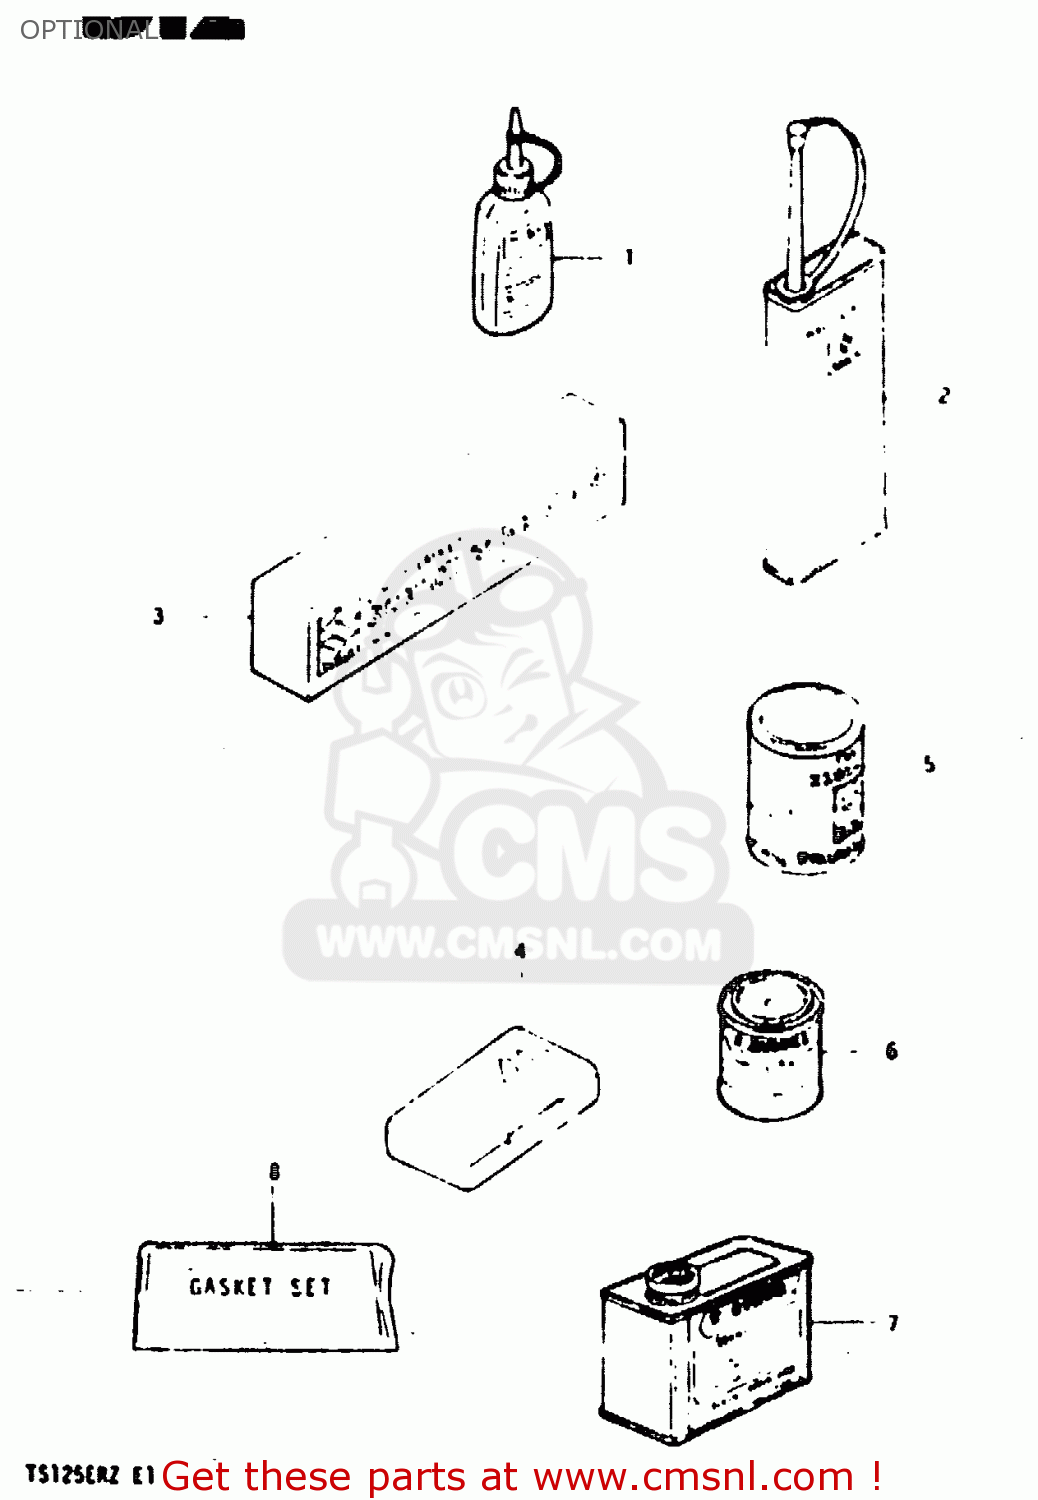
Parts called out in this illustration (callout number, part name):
1	THREAD LOCK NO.1342
2	THREAD LOCK NO.1401 CLEAR 200G
3	BOND 1104
4	TUBE REPARING TOOL
5	GREASE(C)EP2 LITHIUM 150G
6	PAINT,BLACK
7	PAINT (BLACK)
8	GASKET SET (MCA)
